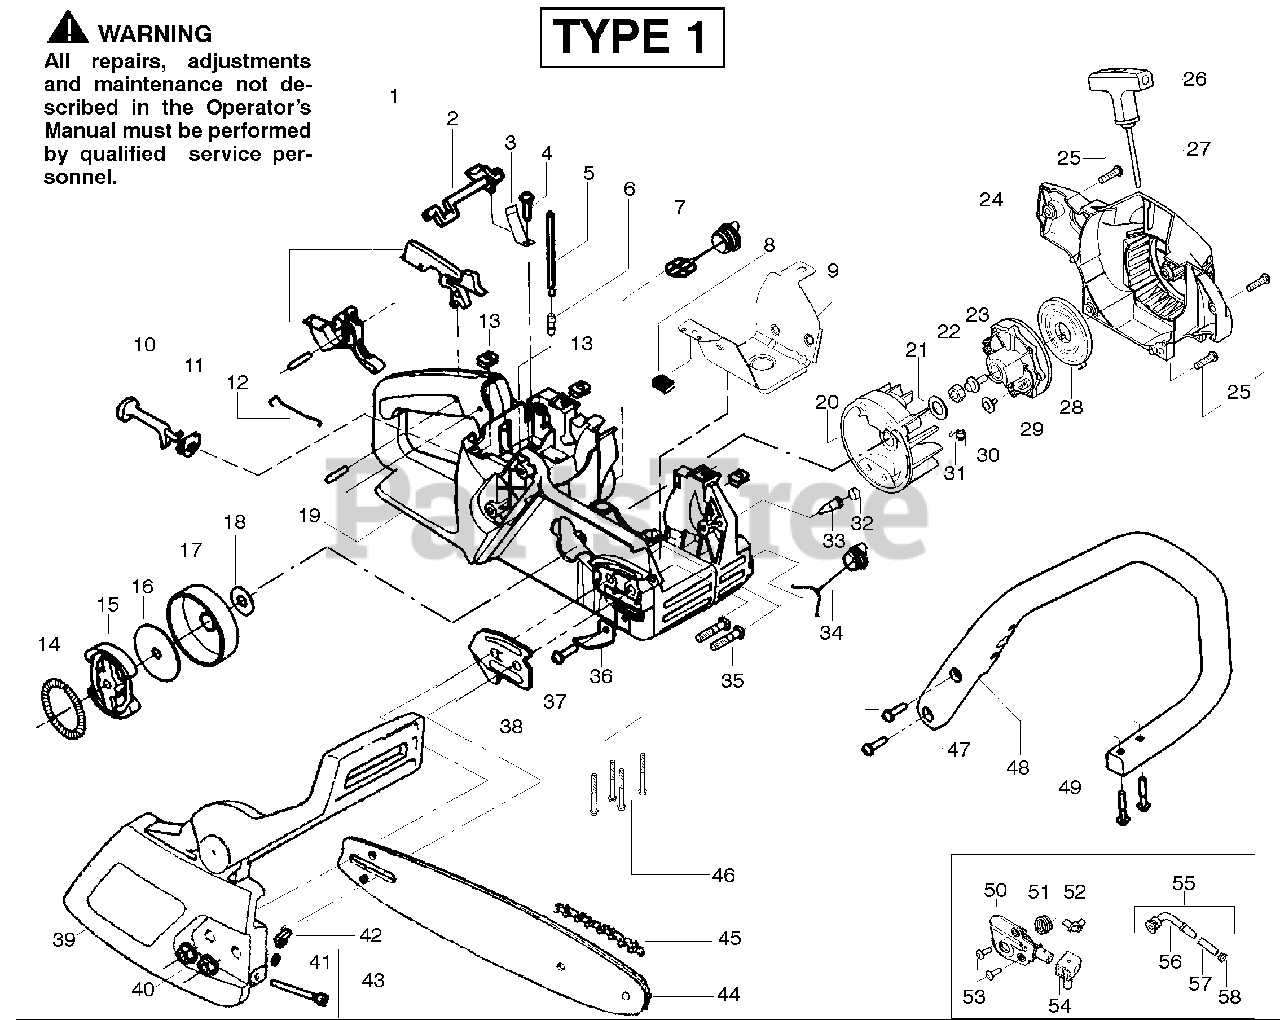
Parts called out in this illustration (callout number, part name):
1	Trigger & Lockout Kit
2	Switch Lever
3	Switch Spring
5	Fuel Line Kit (Large)
6	Fitting - Fuel line
7	Fuel Cap Ass'y.
8	Clip - "U"
9	Shield - Heat
10	Lever-Choke
11	Grommet-Choke lever
12	Wire-Throttle
13	Nut-Speed
14	Spring - Clutch
15	Assy.-Clutch
16	Washer-Clutch
17	Drum Assy. W/brg.
18	Washer - Thrust
19	Kit - Chassis Assy.
20	Flywheel Ass'y.
21	Washer-Flywheel
22	Nut-Flywheel
24	Fan Housing
26	Starter Handle
27	Rope Kit
28	Starter Spring
29	Starter Pulley
31	Spring - Starter Dog
32	Plug - Bronze Vent
33	Check Valve
34	Oil Cap Ass'y.
35	Bolt - Bar
36	Chain Catcher
38	Plate-Bar Mounting
39	Assy.-Chain Brake
40	Nut-Bar Mounting
41	Retainer-Bar Adjust
42	Pin-Bar Adjust
43	Kit-Bar Adjust
45	Chain-14"
48	Front Handle
50	Kit-Oil Pump
51	Gear-Worm Spring
52	Elbow-Oil Pickup
54	Seal Block
55	Oil-Pickup Ass'y.
56	Oiler Pickup
57	Oil Filter
58	Plug-Oil Filter
